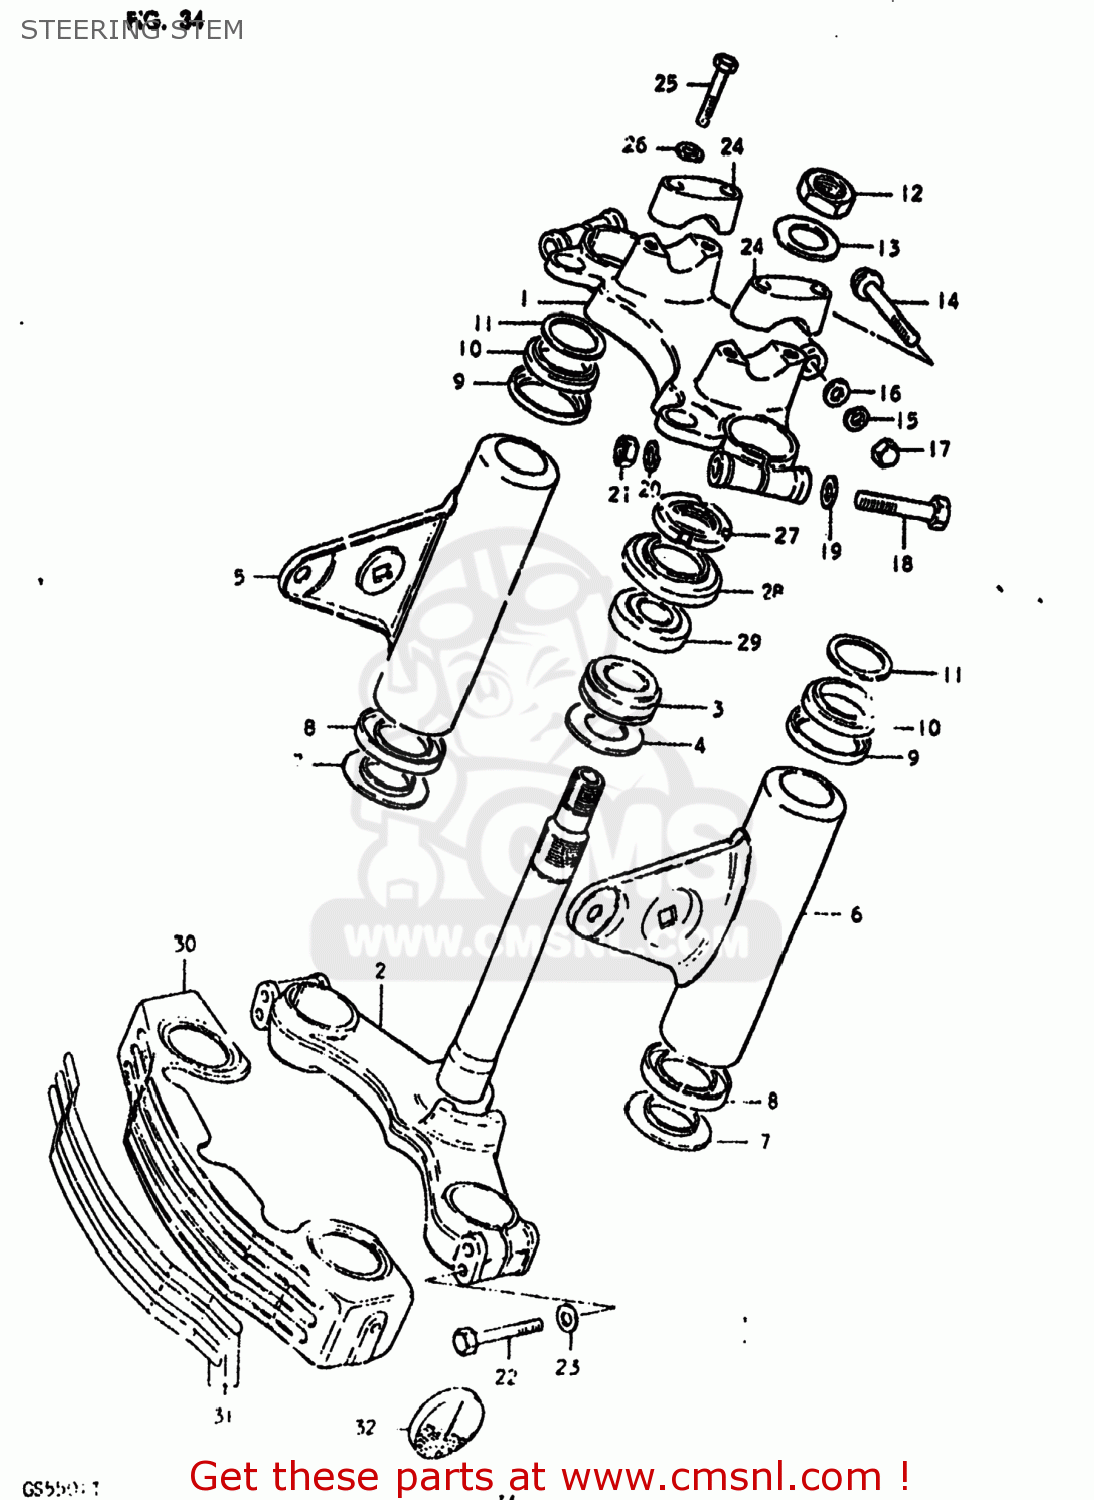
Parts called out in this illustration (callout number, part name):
1	HEAD,STEERING STEM
2	STEM,STEERING
3	BEARING
4	WASHER,THRUST
5	BRACKET,HEADLAMP,RIGHT
6	BRACKET,HEADLAMP,LEFT
7	GUIDE
8	CUSHION,HEADLAMP BRACKET
9	GUIDE
10	CUSHION,HEADLAMP BRACKET UPR
11	SEAT
12	NUT,FR FORK UPR BRACKET
13	WASHER
14	BOLT
15	LOCK WASHER
16	WASHER
17	NUT,M8X1.25X12
18	BOLT 10X55
19	WASHER 5MM
20	LOCK WASHER
21	NUT 10MM
22	BOLT 8X45
23	WASHER,LOCK,8.
24	HOLDER,HANDLE UPR
25	BOLT
26	LOCK WASHER
27	NUT,STEERING STEM(25X44X10)
28	DUST SEAL,STEERING,UPPER
29	TAPER,ROLLER BEARING
30	COVER,FRONT FORK
31	TAPE SET,FRONT FORK COVER
32	REFLEX REFLECTOR,RR
